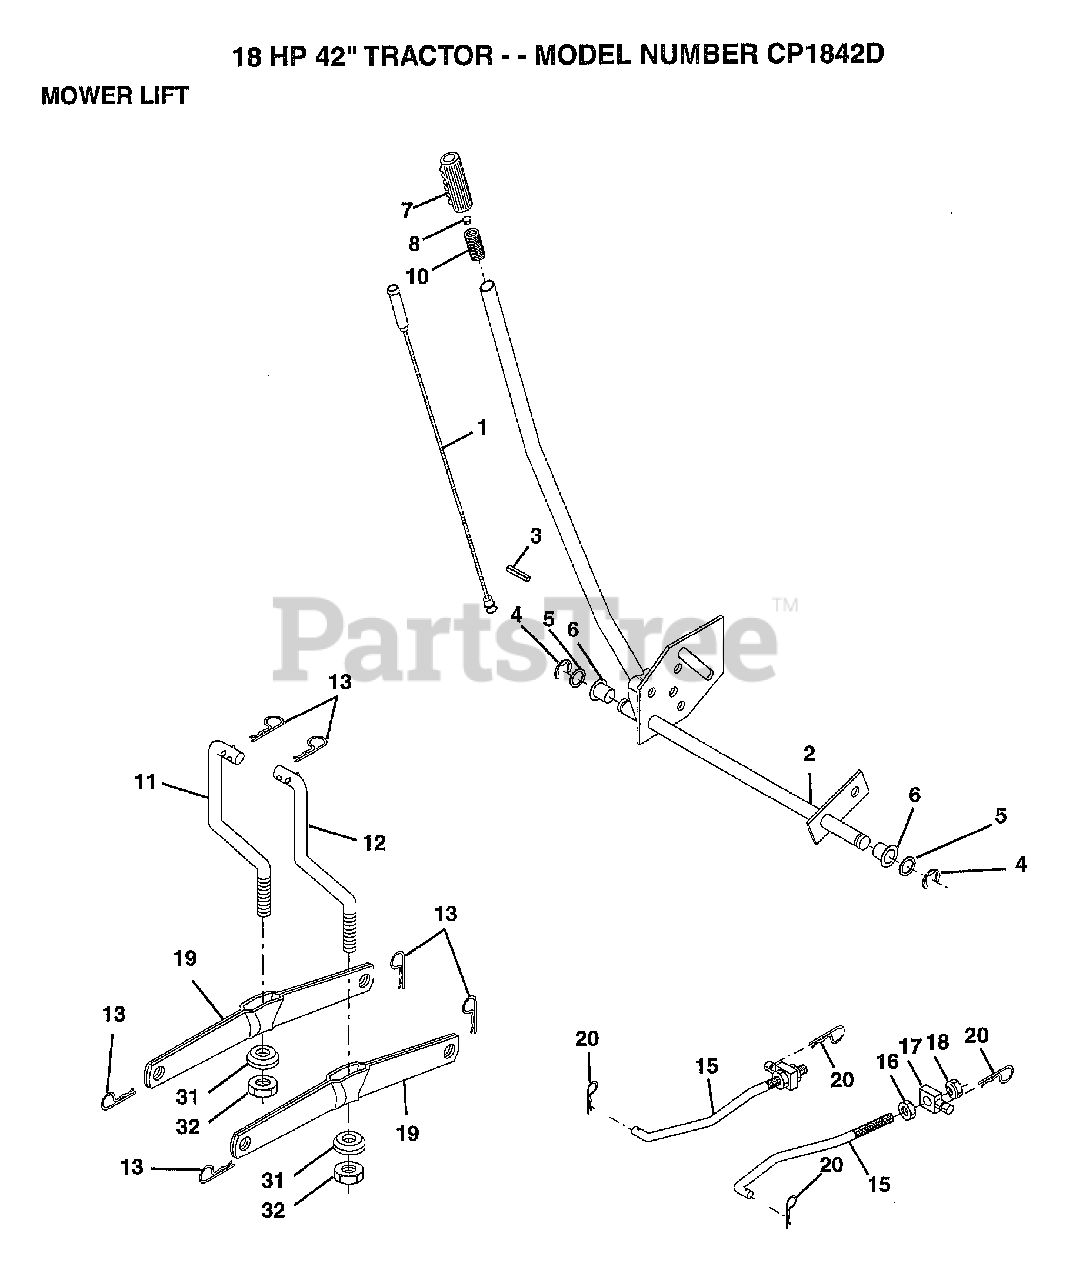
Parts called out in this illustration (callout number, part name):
1	WIRE ASM
2	SHAFT.ASM.LIFT LH
3	PIN GROOVE
5	WASHER
6	NYLON BEARING
7	GRIP
15	LINK.FRONT
16	NUT
17	TRUNION
18	NUT.LK.W/WSH.1/2.
19	ARM SUSP REAR
20	RETAINER.SPRING
31	BEARING PVT LH
32	NUT.LOCK.3/8-24
